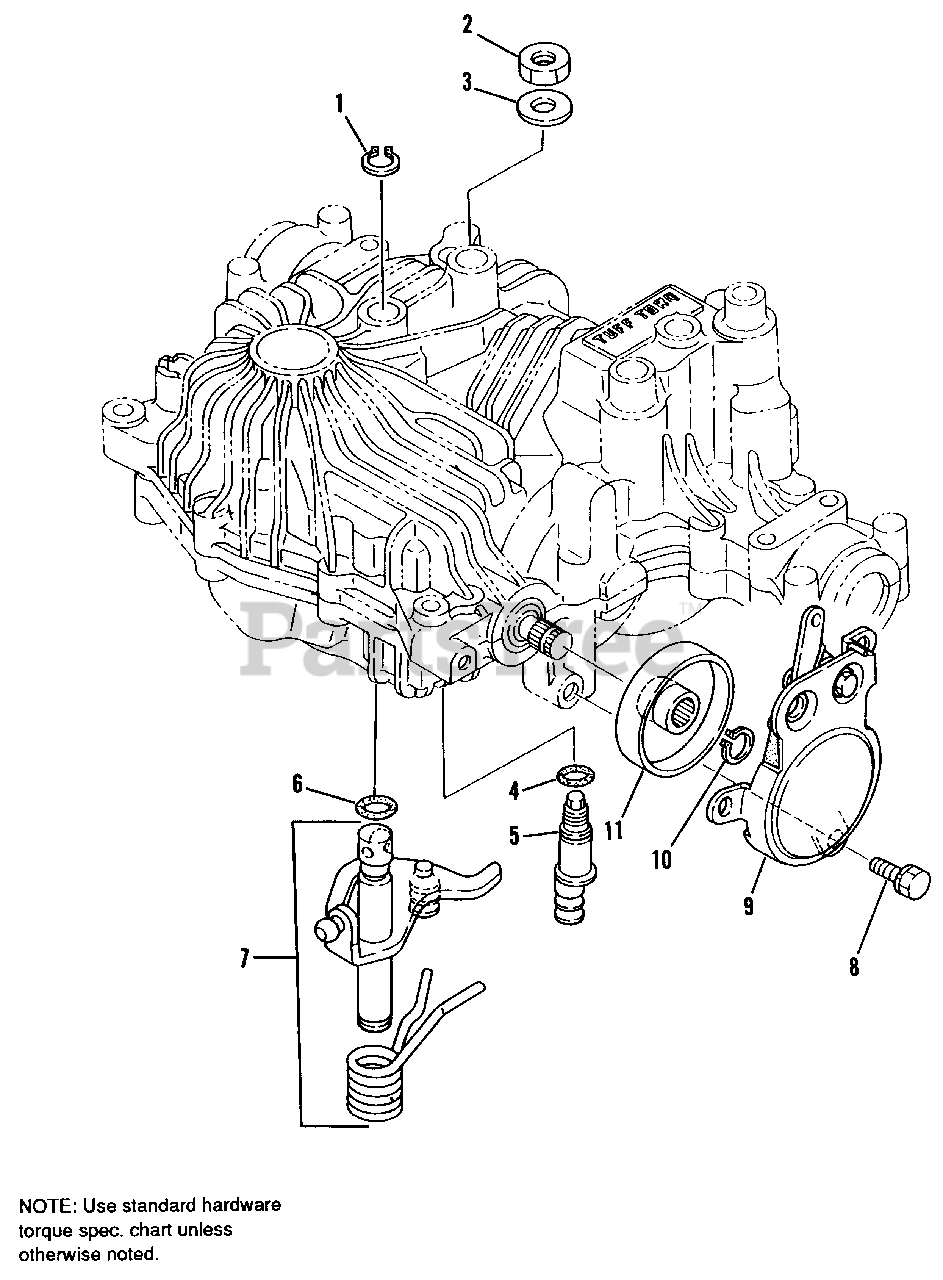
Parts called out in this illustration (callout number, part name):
1	RING, Retaining
4	O-RING, 1A P10A
6	PACKING
7	SHAFT, Control
10	RING, Retaining
11	DRUM, Brake
